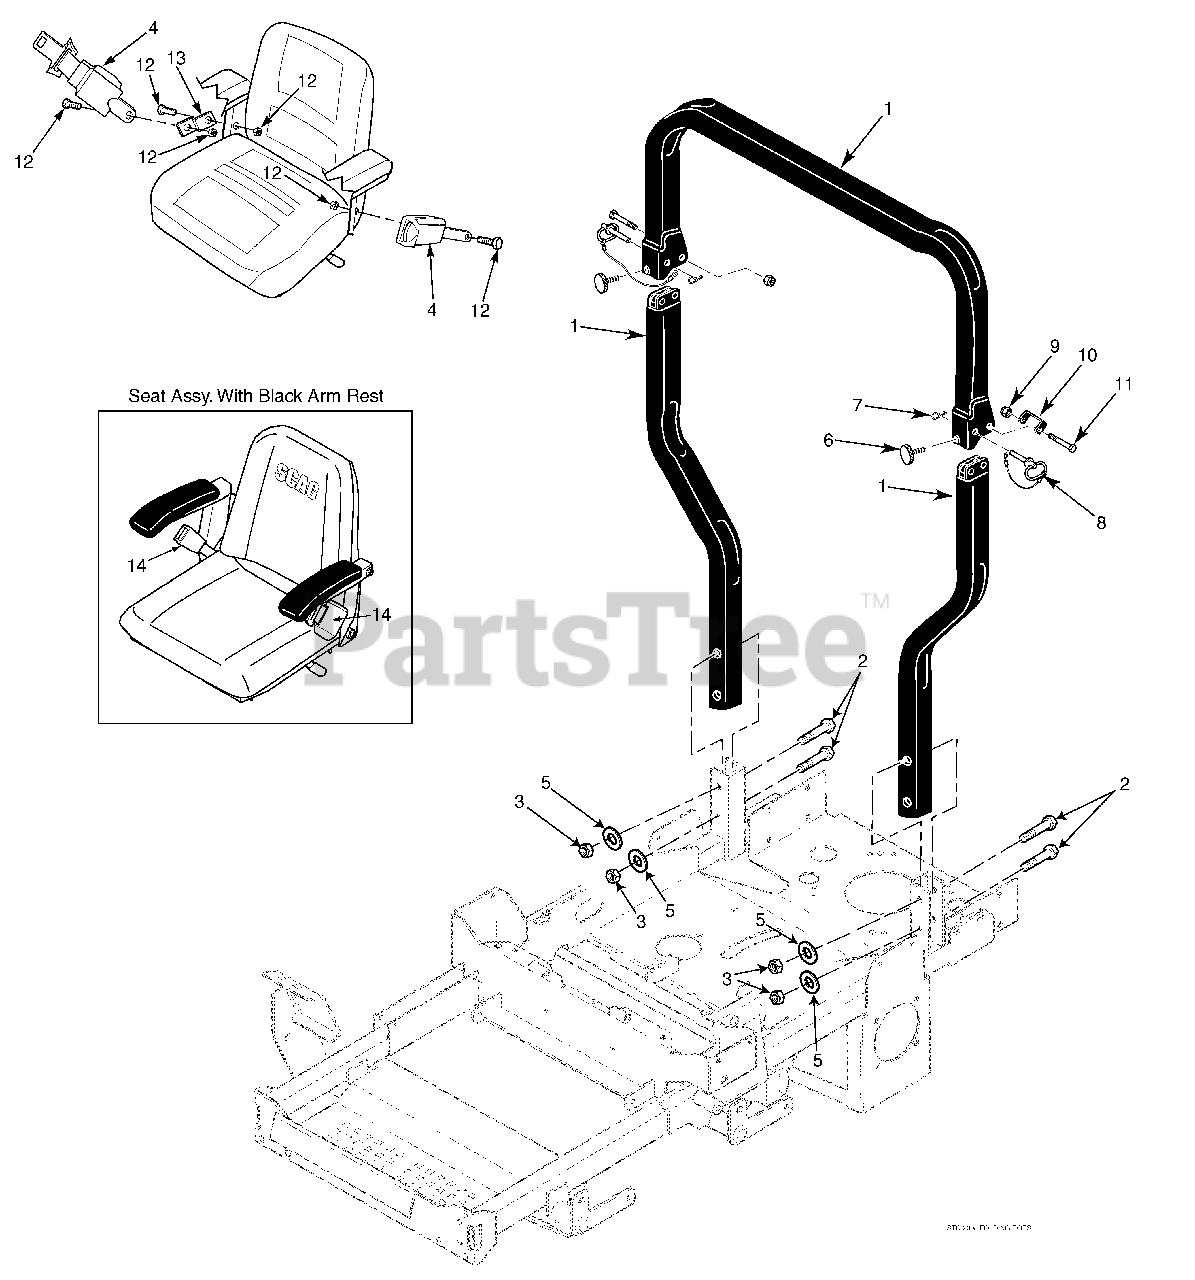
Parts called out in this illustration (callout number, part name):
1	STC Foldable ROPS Accessory
2	Bolt, Hex Head 1/2-13 x 3-1/2"
3	Nut, Center Lock 1/2-13
4	Retractable Seat Belt
5	Flatwasher, 1/2-.562 x 1.375 x .109
6	Thumb Screw, 5/16-18 NC x 3/4"
7	Hair Pin, Cotter
8	Pin
9	Nut, Center Lock 1/2-13
10	Bracket, Stop
11	Bolt, Hex Head 1/2-13 x 3-1/2"
12	Seat Hardware Kit, STC
13	Bracket
14	Retractable Seat Belt
